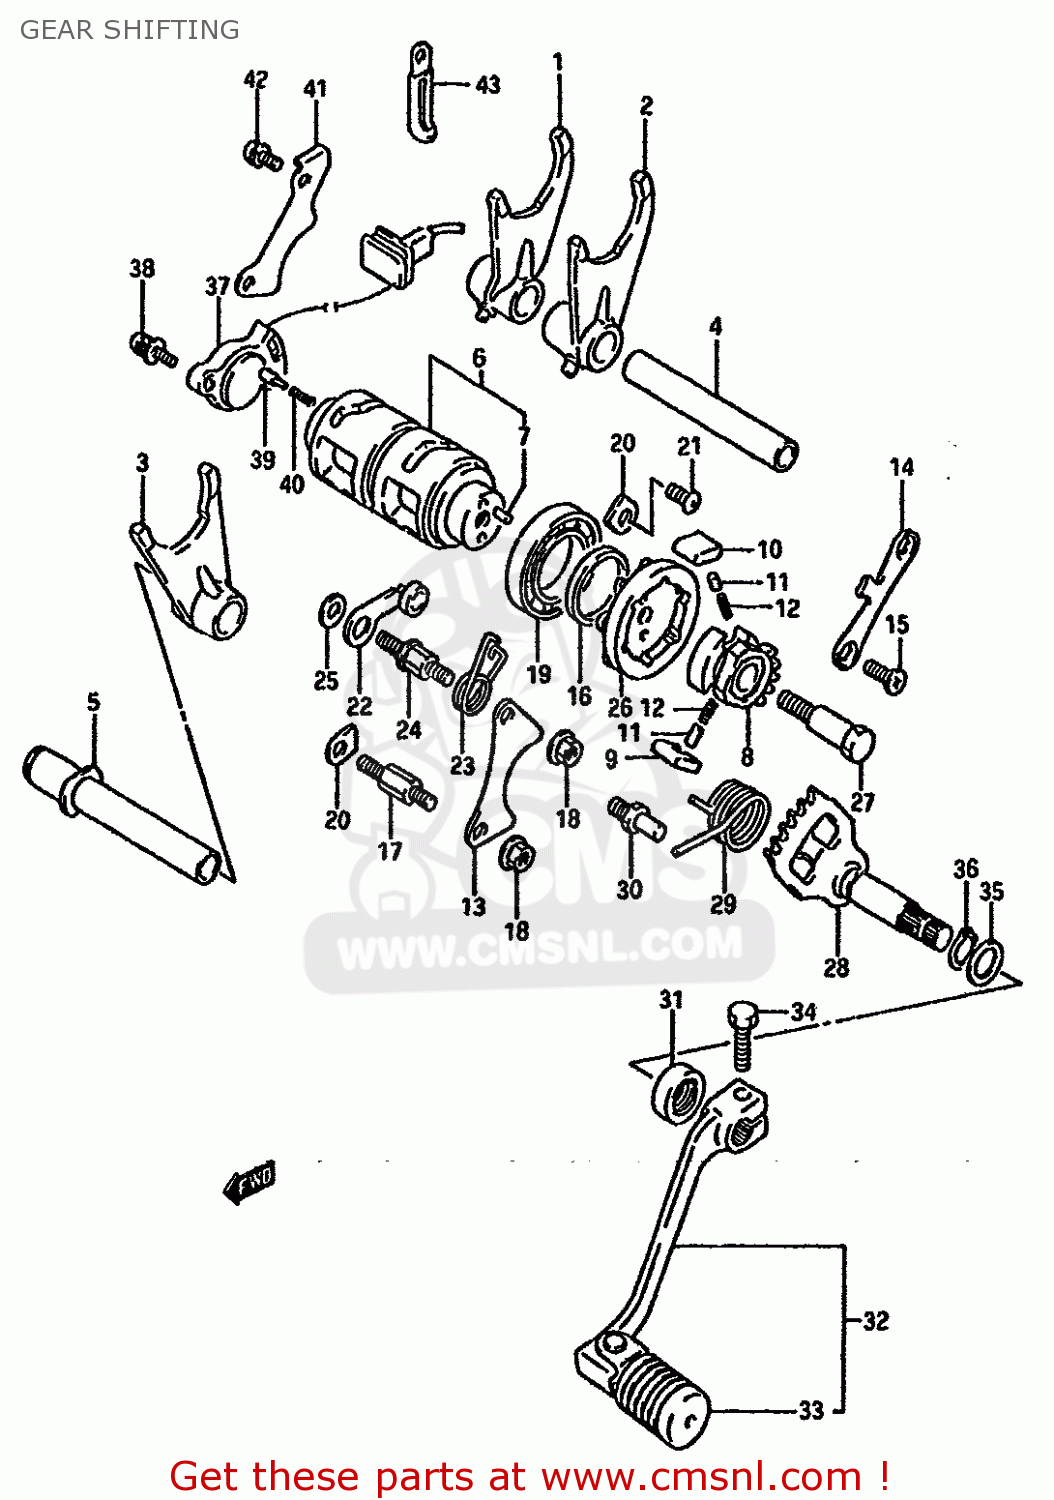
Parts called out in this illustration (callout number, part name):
1	FORK,GEAR SHIFT NO.1
2	FORK,GEAR SHIFT NO.2
3	FORK, GEAR SHIFTING NO.3
4	SHAFT,GEAR SHIFT FORK NO.1
5	SHAFT,FORK NO.2
6	CAM,GEAR SHIFT
7	PIN
8	GEAR,GEARSHIFT CAM DRIVE
9	PAWL,GEAR SHIFT NO.1
10	PAWL,GEAR SHIFT NO.2
11	PIN(5X8)
12	SPRING
13	LIFTER,GEAR SHIFT POLE
14	GUIDE,GEAR SHIFT CAM
15	SCREW
16	WASHER(25X32X3)
17	BOSS,SHIFT PAWL LIFTER
18	NUT
19	BEARING
20	RETAINER,SHIFT CAM,R BEARING
21	SCREW 6X12
22	STOPPER,GEAR SHIFT CAM
23	SPRING
24	SPRING,STOPPER ARM
25	WASHER
26	PLATE,GEAR SHIFT CAM
27	PIN,SHIFT CAM DRIVEN GEAR
28	SHAFT,GEAR SHIFT
29	SPRING
30	STOPPER,GEAR SHIFT ARM
31	OIL SEAL
32	LEVER ASSY,GEAR SHIFTING
33	RUBBER,GEAR SHIFT PEDAL
34	BOLT
35	WASHER
36	CIRCLIP
37	BASE ASSY,NEUTRAL SW TERMINAL
38	SCREW
39	PIN(5X15.5)
40	SPRING
41	CLAMP, LEAD WIRE
42	SCREW
43	CLAMP L:35
